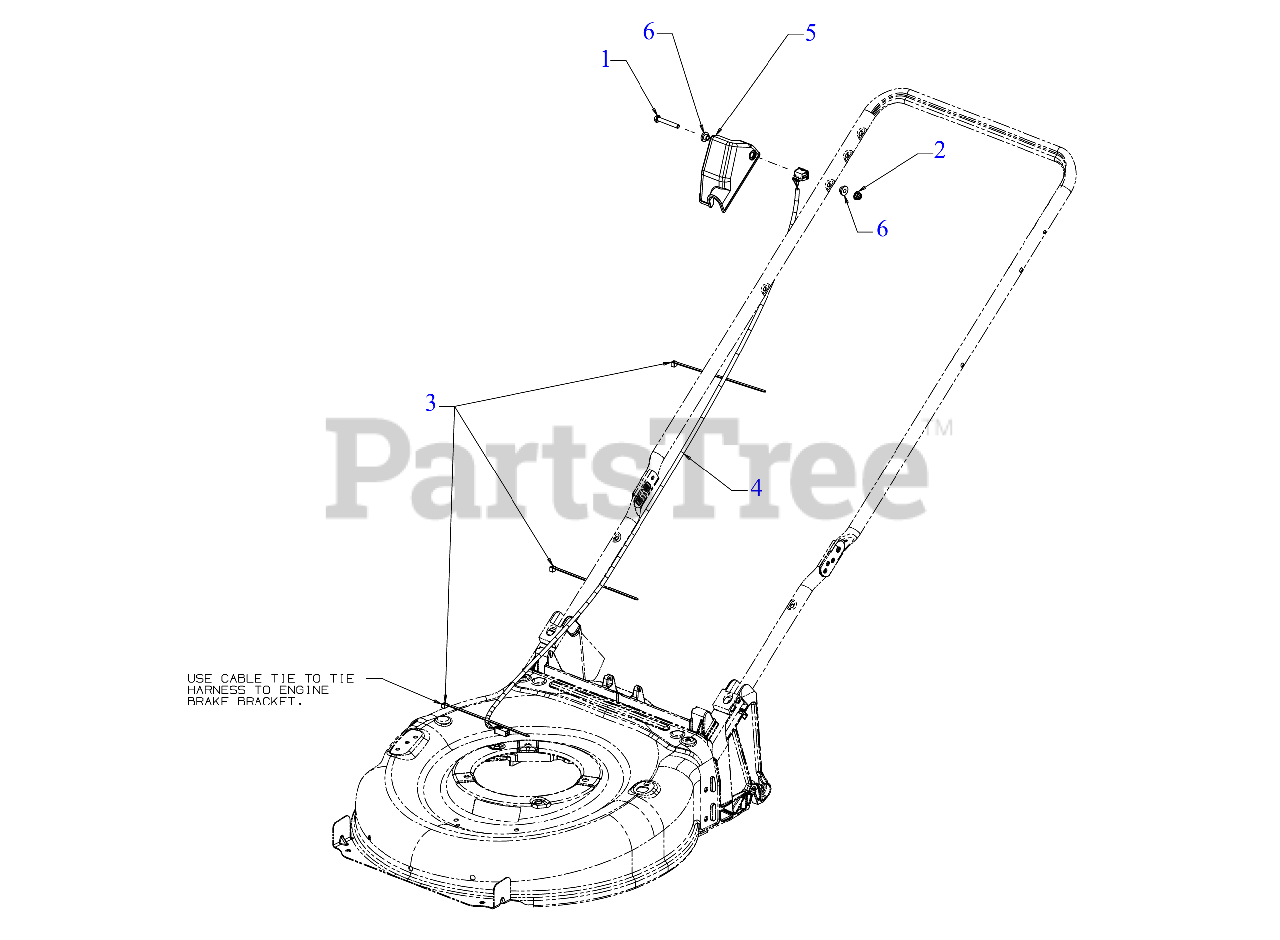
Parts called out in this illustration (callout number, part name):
1	HEX SCREW 1/4-20 x 1.75
2	FLANGE LOCK NUT
3	7" CABLE TIE
4	HARNESS (159cc)
5	STOP SWITCH HOUSING
6	SHOULDER SPACER
